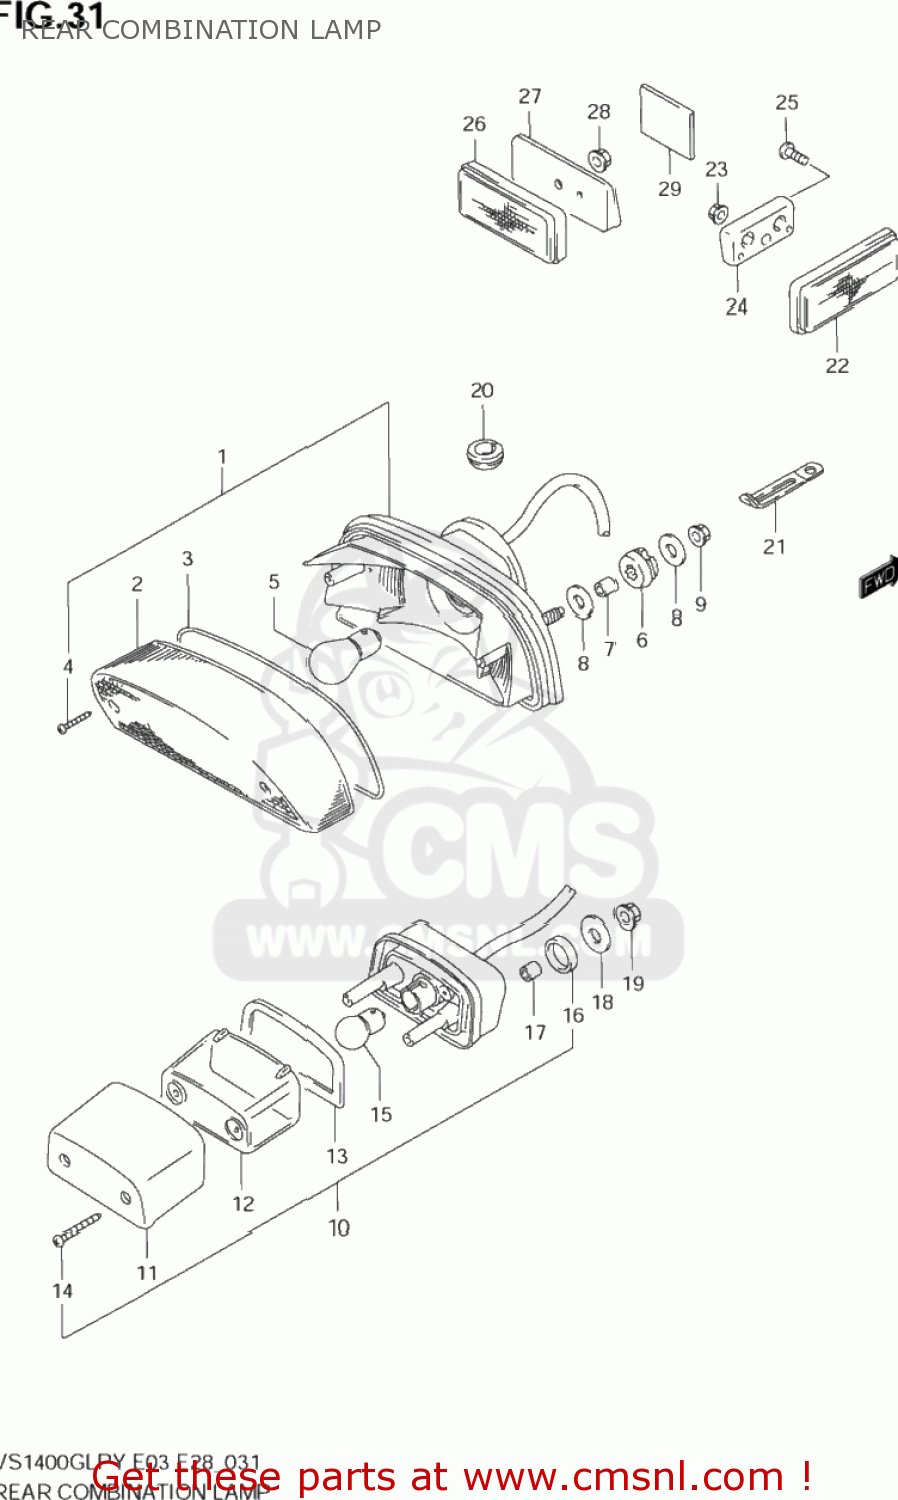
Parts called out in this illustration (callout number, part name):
1	LAMP ASSY,RR COMBINATION
2	LENS
3	GASKET (NAS)
4	SCREW
5	BULB(12V27/8W)
6	CUSHION
7	SPACER(6.5X9X10.5)
8	WASHER(6.5X20X1.2)
9	NUT
10	LAMP ASSY,LICENSE
11	COVER,LICENSE LAMP
12	LENS,LICENSE LAMP
13	GASKET,LICENSE LAMP (NAS)
14	SCREW
15	BULB(12V7.5W)
16	CUSHION
17	SPACER
18	WASHER(6.5X20X1.2)
19	NUT
20	GROMMET
21	CLAMP(L:45)
22	REFLECTOR ASSY,RR
23	NUT
24	SPACER,RR SIDE REFLECTOR
25	SCREW
26	REFLECTOR ASSY,RR
27	SPACER,RR REFLECTOR
28	NUT
29	TAPE,TOOL BAG PROTECTOR
